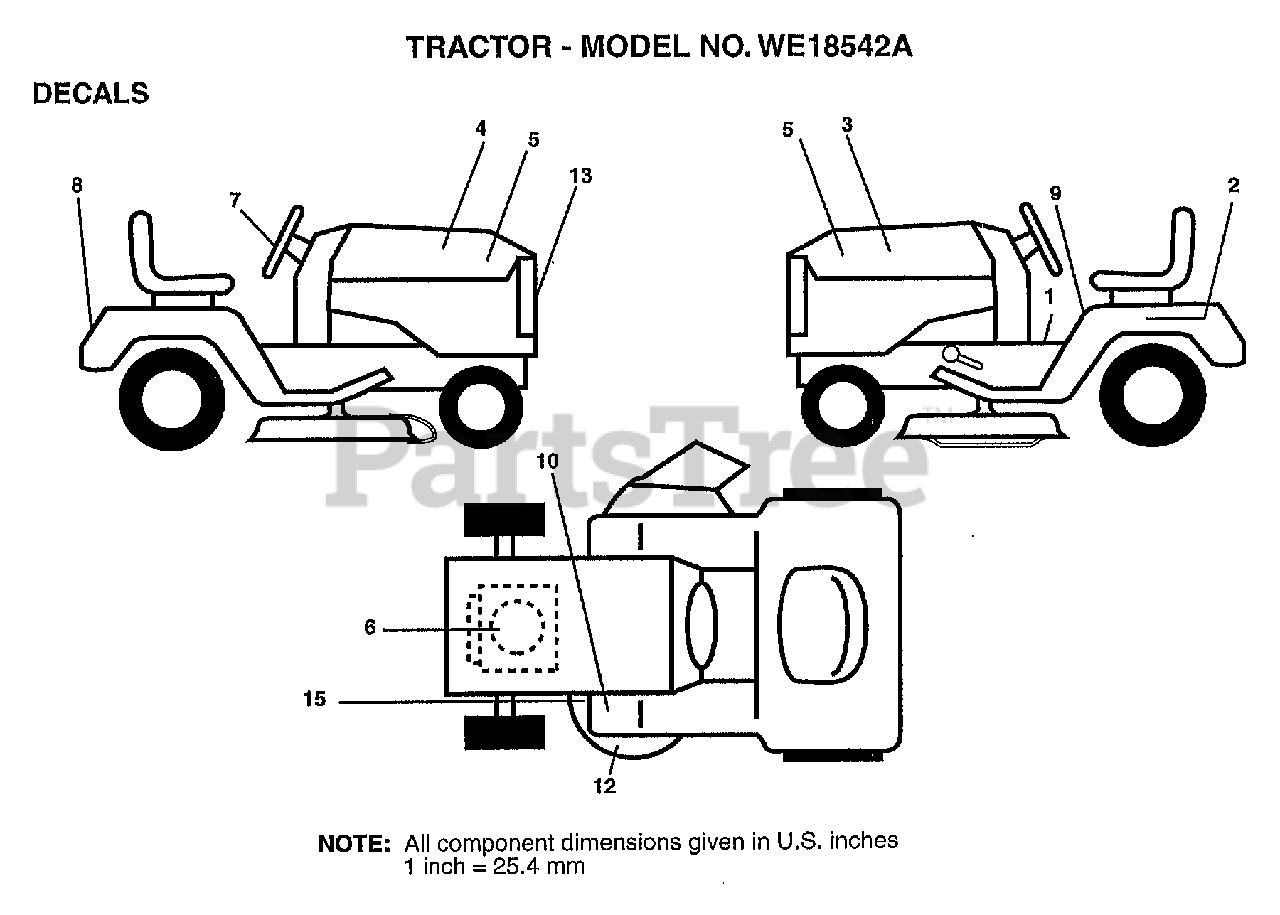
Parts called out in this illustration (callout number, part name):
1	"DECAL DASH,OPER."
2	DECAL.BATRY.3-3908
3	DECAL HOOD LH
4	"DECAL HOOD,RH"
5	"DECAL.PANEL,SIDE"
6	DECAL, HP, ENGINE
7	"DECAL INS,STRG WH"
8	DECAL-FENDER
9	"DECAL DANGER,FEND"
13	"DECAL GRILLE,LENS"
15	DECAL
